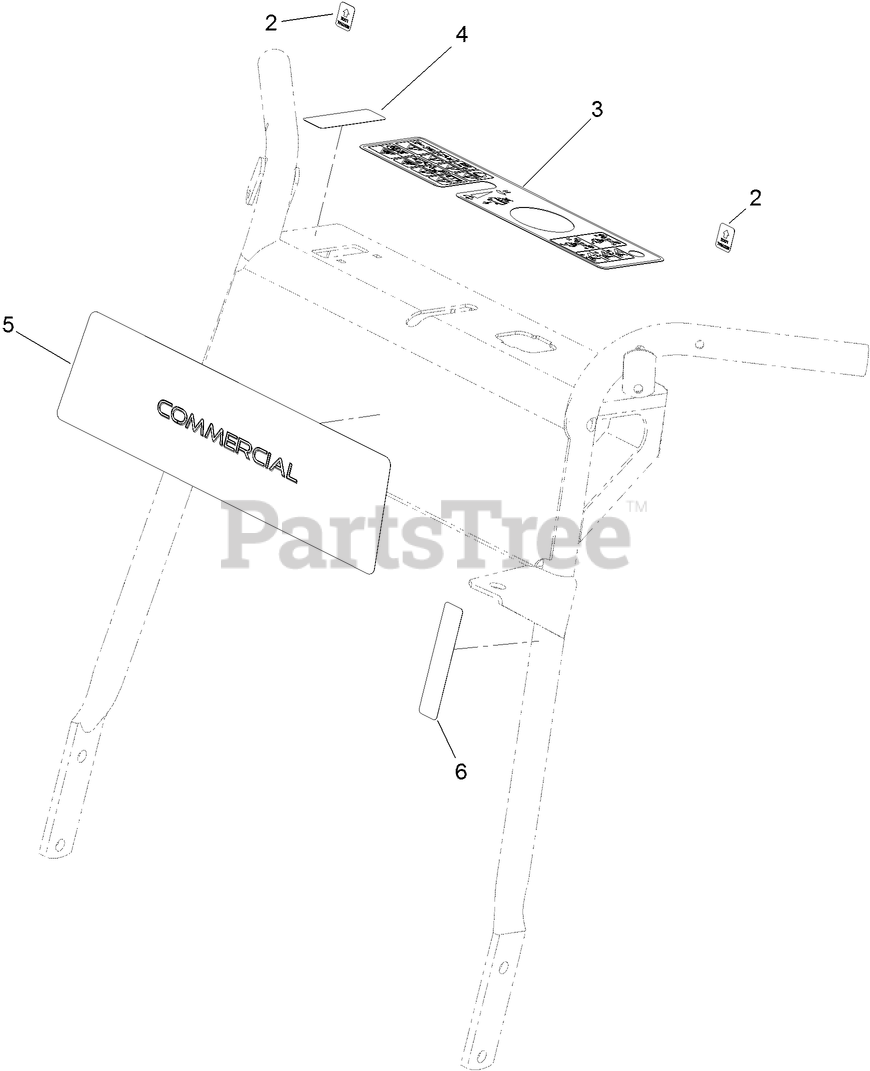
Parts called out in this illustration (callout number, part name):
2	DECAL-LOCK, NEUTRAL
3	DECAL-CONTROL PANEL
4	DECAL-THROTTLE
6	DECAL-ENGAGE, DECK
